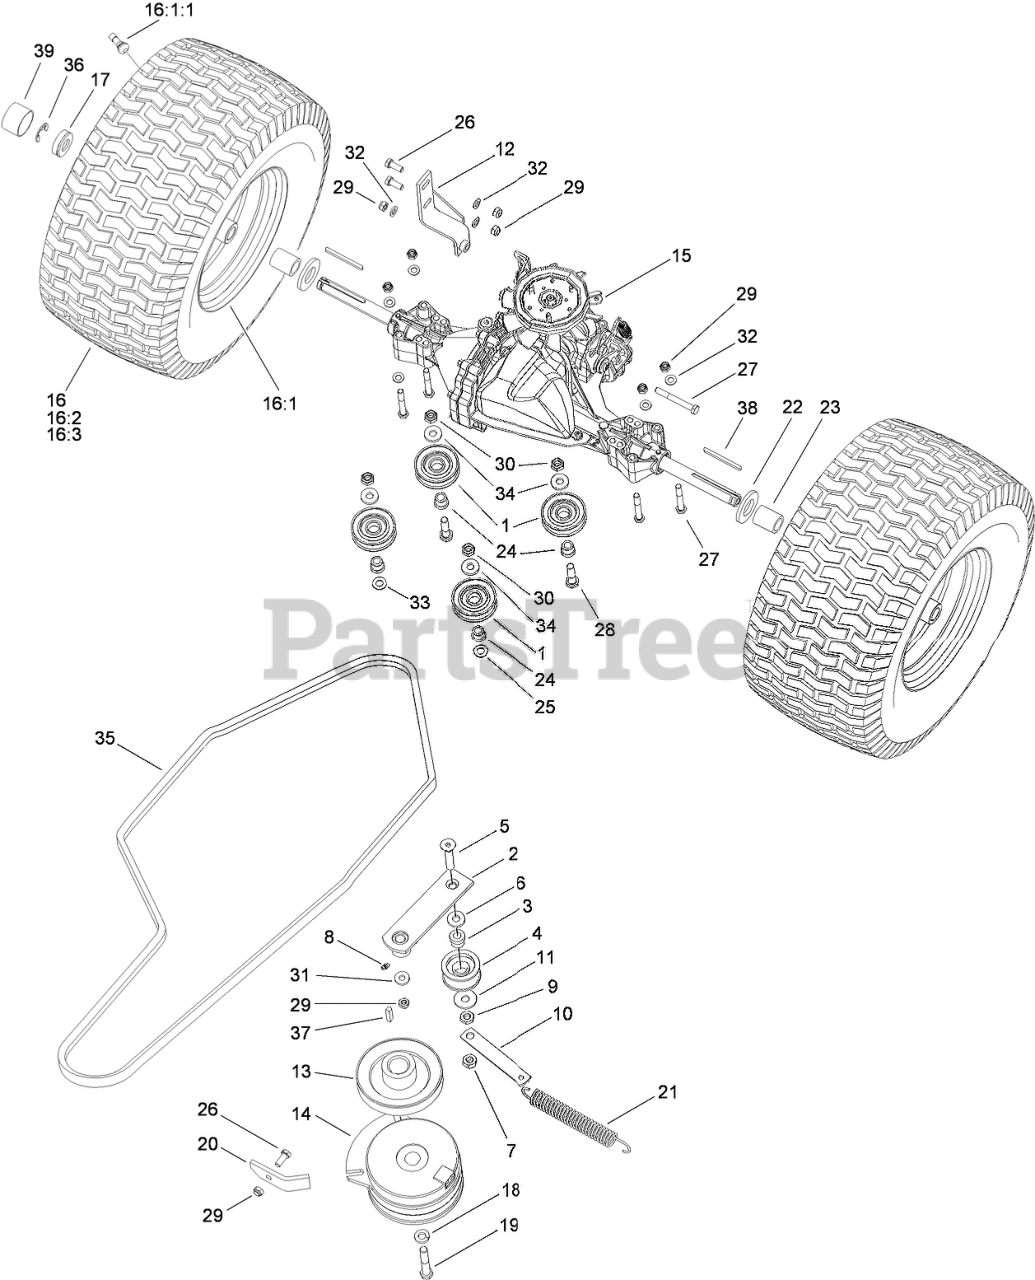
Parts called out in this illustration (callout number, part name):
1	PULLEY-IDLER
2	ARM-IDLER
3	BUSHING-IDLER
4	PULLEY-IDLER
6	WASHER-FLAT
7	NUT-LOCK
8	FITTING-GREASE
9	NUT-HEX
10	BRACKET-TENTION
11	WASHER
12	BRACKET
13	PULLEY-ENGINE
14	CLUTCH-ELECTRIC
15	TRANSMISSION ASM
16	WHEEL ASM
16:1	RIM-REAR
16:1:1	Valve-Tire
16:3	Tube
17	RETAINER-CAP, HUB
18	WASHER-SPRING, BELLEVILLE
19	SCREW-HH
20	BRACKET-RETAINER
21	SPRING
22	WASHER
23	SPACER-AXLE
24	BUSHING
25	SPACER
26	SCREW-HH
27	CAPSCREW
28	SCREW-HH
29	NUT-LOCK, NI
30	NUT-LOCK
31	WASHER-PLAIN
32	WASHER-PLAIN
33	Washer
34	WASHER-FLAT
35	V-BELT, TRACTION
36	CLIP-SPRING
37	KEY-SQUARE
38	KEY-SQUARE
39	CAP-HUB
